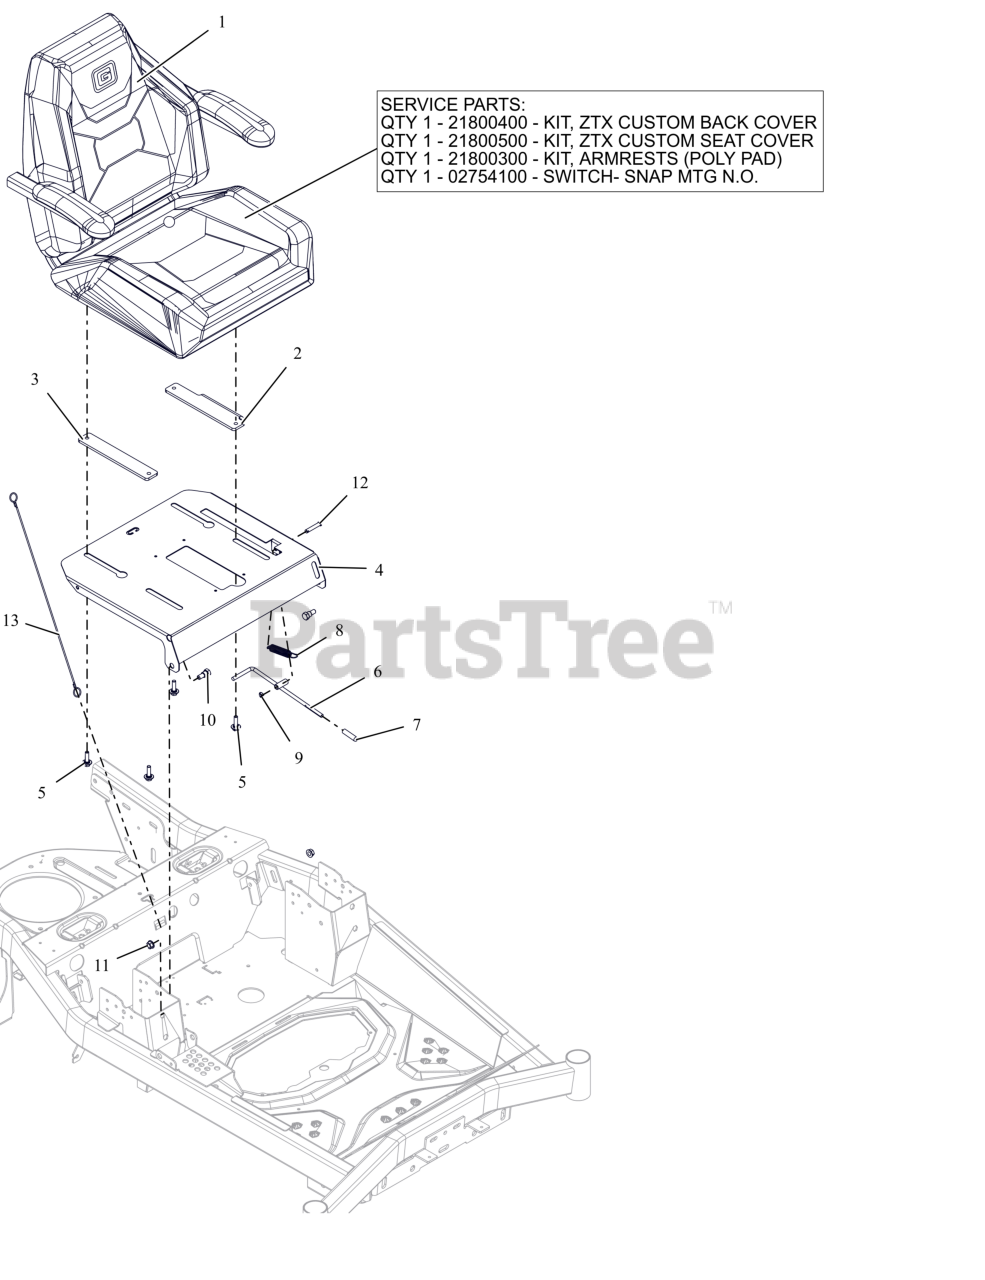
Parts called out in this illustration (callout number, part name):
1	SEAT- ZTX MY23 (WOOD)
1	KIT- ZTX CUSTOM BACK COVER
1	KIT- ZTX CUSTOM SEAT COVER
1	KIT- ARMRESTS ( POLY PAD)
1	SWITCH- SNAP MTG N.O.
2	ADJUSTER-PLATE-SEAT
3	SPCR- SEAT PLATE
4	PLATE-SEATE
5	BLT, SHLDR .31-18 X .100
6	WLDMT- LATCH- SEAT
7	GRIP- BLACK .31X1.50
8	SPRG, EXT .653 X .063 X 2.755
9	NUT-PUSH .312
10	BLT-SHLDR .50X.38 ZCC
11	NUT-LK-CTR-FLG .375-16 GF ZCC
12	PIN, CLEV .309X1.75 ZCC
13	LANYARD, SEAT CABLE .093X19.5
